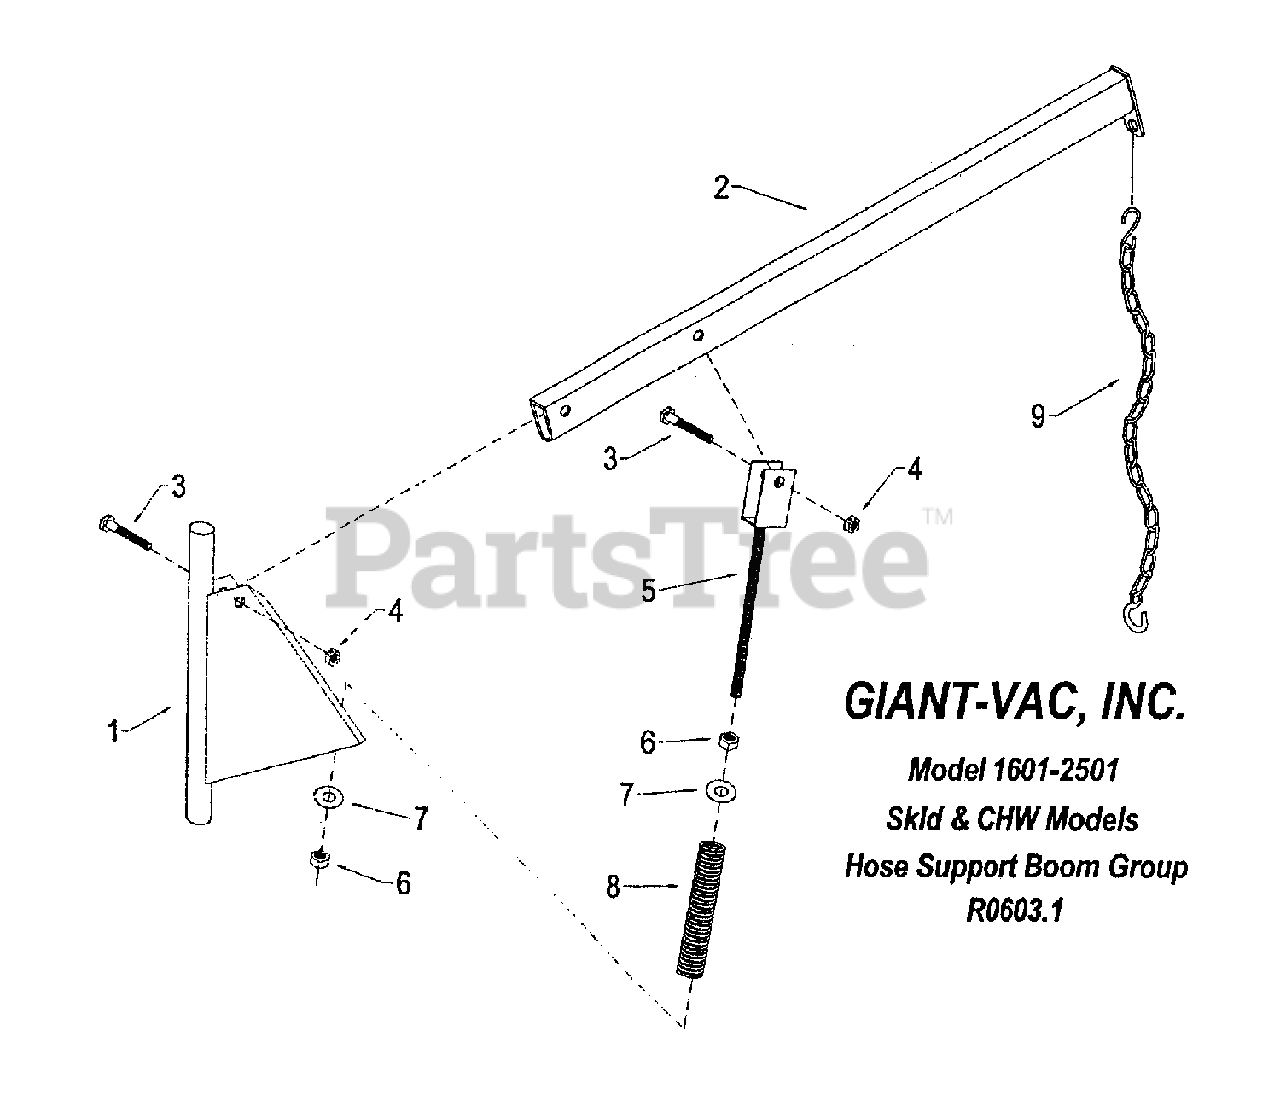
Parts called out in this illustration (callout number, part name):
1	Boom vertical member
2	Boom horizontal member
3	Bolt, hex -1/2-13 x 3"
4	Nut, reverse lock -1/2-13
5	Guide, threaded spring
6	Nut, hex-3/4-10
7	Washer, flat-3/4"
8	Spring, boom
9	Chain, boom -48" w/2 S-hooks
